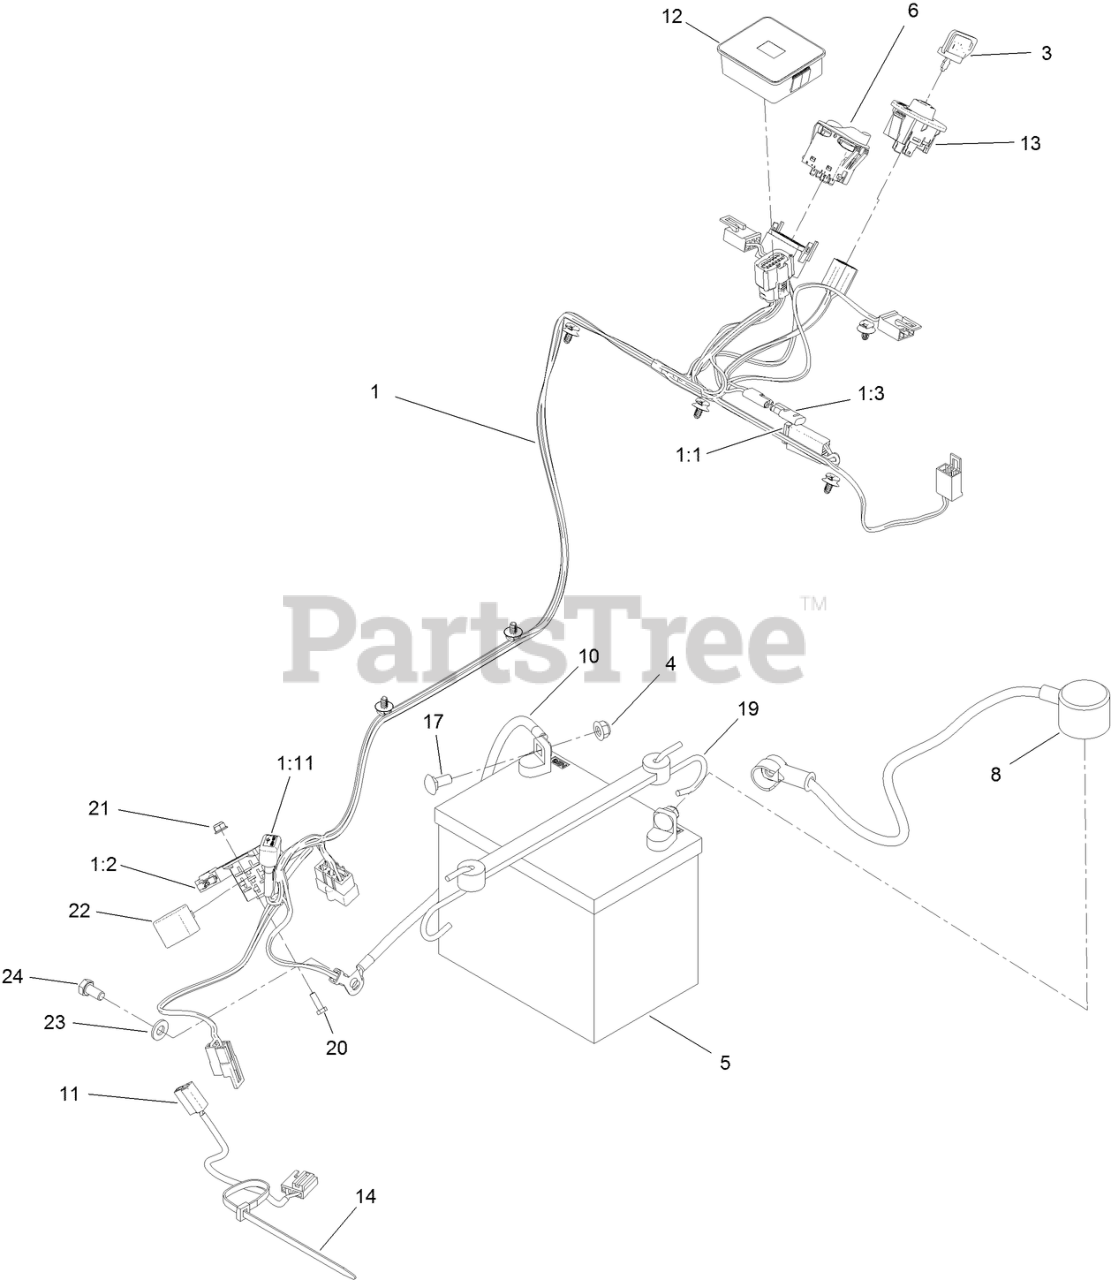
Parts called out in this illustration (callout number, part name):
1	HARNESS-WIRE, WASP
1:1	FUSE-BLADE, 15 AMP
1:2	FUSE-BLADE, 25 AMP
1:3	CAP-PLUG
3	KEY-IGNITION
4	NUT-HF, NI
5	BATTERY
6	SWITCH-ROCKER, (ON)-ON-OFF
8	CABLE-BATTERY, POSITIVE
10	CABLE-BATTERY, NEG ASM
11	HARNESS-CLUTCH PIGTAIL
12	MODULE, HOUR METER
13	SWITCH-IGNITION
14	TIE-CABLE
17	BOLT-CARR
19	HOLDDOWN-BATTERY
21	NUT-HF
23	WASHER-PLAIN
24	SCREW-HH
